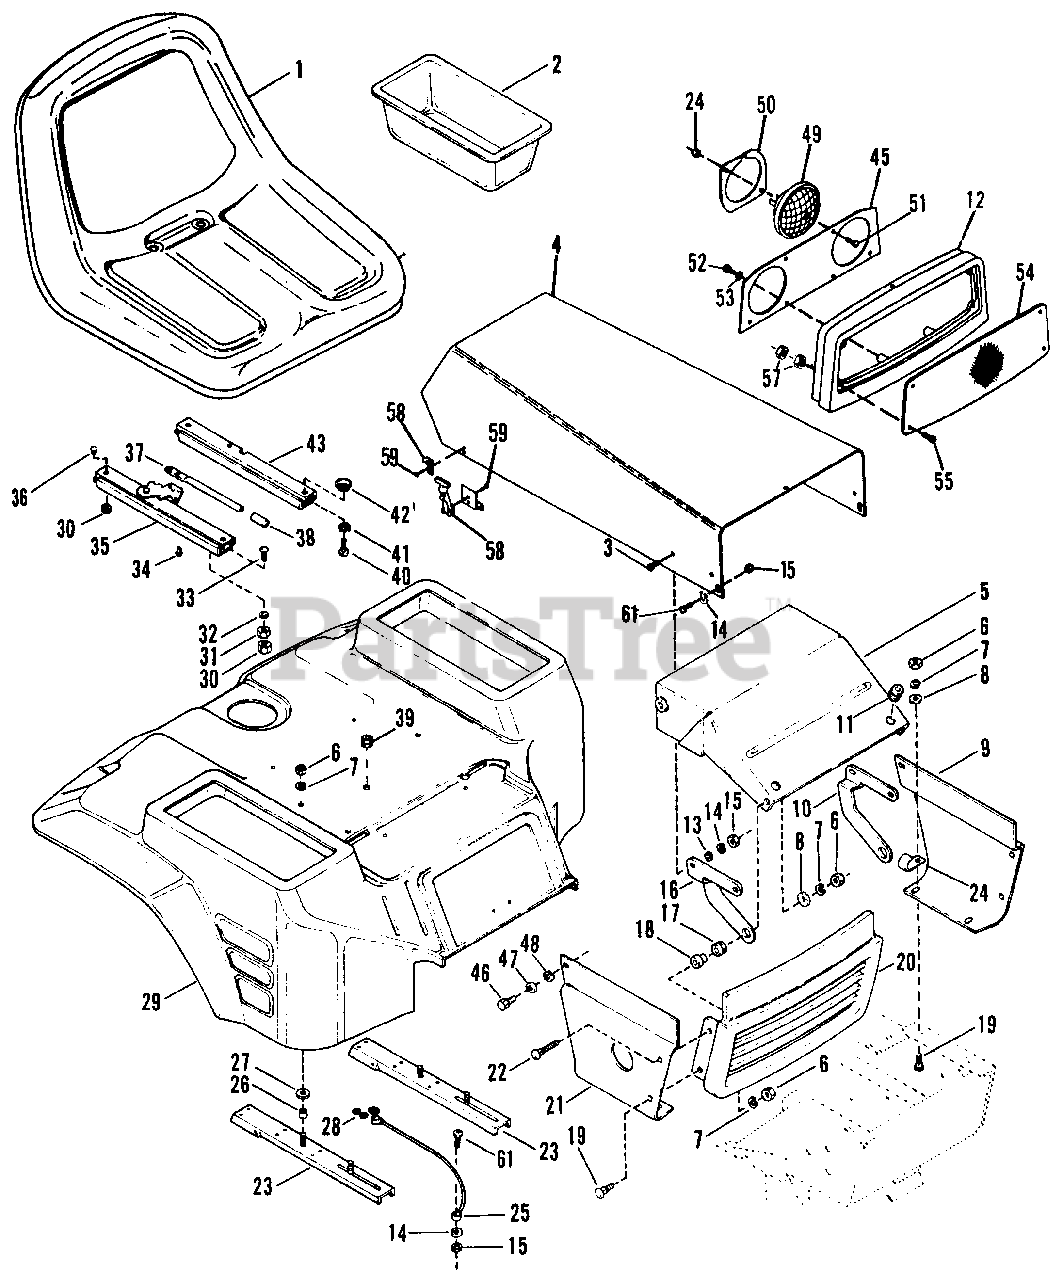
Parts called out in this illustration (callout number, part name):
1	Seat, High Back
2	Tray
3	Bolt, 1/4-20 x .75 Rd Hd Sq Nk
4	Hood, Silk Screen
5	Muffler Shield
6	Nut, Hex 3/8-16
7	Washer, Lock 3/8 Reg.
8	Washer, Flat .438 x 1.000 x .083
9	Panel, Side L.H.
10	L.H. Hood Hinge
11	Grommet
12	Bezel, Headlight
13	Washer, Flat .281 x .625 x .065
14	Washer, Lock 1/4 Reg.
15	Nut, Hex 1/4-20
16	R.H. Hood Hinge
17	Grommet
18	Spacer
19	Bolt, 3/8-16 x 1.00 Rd Hd Sq Nk
20	Casting, Grille
21	Panel, Side R.H.
22	Bolt, 3/8-16 x 2.00 Rd Hd Sq Nk
23	Seat Support
24	Nut, Lock 1/4-20
25	Cable
26	Spacer
27	Washer, .380/.390 x .750 x .125
28	"S" Hook
29	Rear Deck
30	Nut, Lock 5/16-18
31	Nut, Hex 5/16-18
32	Washer, Lock 5/16 SP
33	Screw, Cap BTHD 5/16-18 x .875
34	Pop Rivet
35	Seat Slide, R.H.
36	Screw, Cap BTHD 5/16-18 x .50
37	Seat Slide Handle
38	Grip
39	Grommet
40	Screw, Mach. 5/16-18 x 1.00 Rd Hd
41	Washer, Lock 5/16 Ext.
42	Spacer
43	Seat Slide, L.H.
44	Clip
45	Panel, Headlight Reflector
46	Screw, Machine 5/16-18 x .75
47	Washer, Flat .375 x .734 x .065
48	Washer, Lock 5/16 Int. Tooth
49	Headlight
50	Headlight Retainer Ring
51	Bolt, Hex 1/4-20 x 1.25
52	Screw, Tapping 1/4-20 x .625
53	Washer, Lock 1/4 Ext.
54	Panel, Headlight Lens
55	Screw, Mach. 10-24 x .75 PHD
57	Nut, Hex 10-24
58	Latch, Flexible
59	Rivet, Pop Domed 1/8 x .294
60	Screw, 1/4-20 x .75 Torx Slotted Ph Pl
NS	Decal, Side Stripe R.H. and L.H.
NS	Decal, Model 18-H
NS	Decal, Gravely Logo
NS	Decal, Maintenance Instructions
